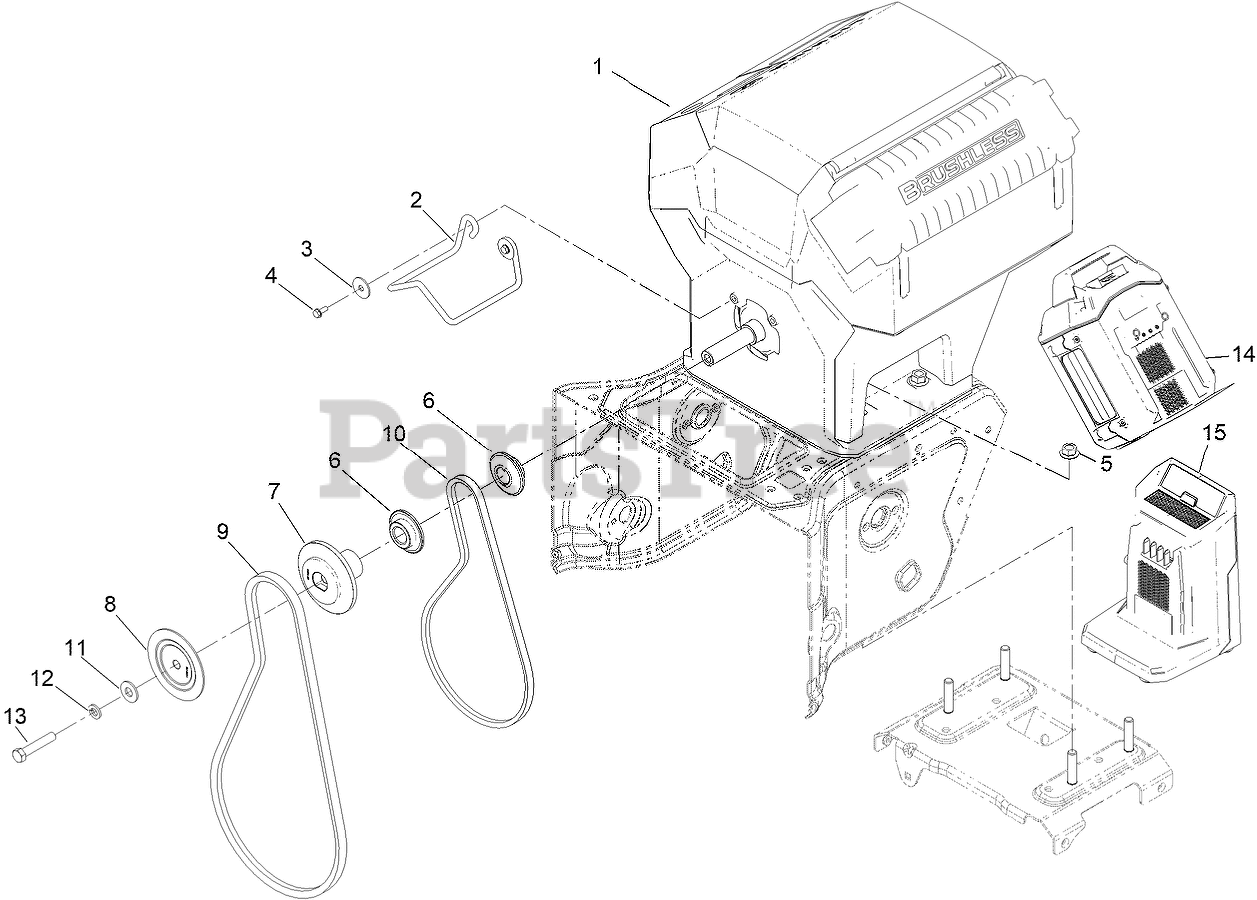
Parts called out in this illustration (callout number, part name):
1	POWERHEAD-60V
2	GUIDE-BELT
3	WASHER-FLAT
4	SCREW-HWH, THD ROLL
5	NUT-LOCK
6	PULLEY-ENGINE, TRACTION
7	PULLEY-AUGER, REAR
8	PULLEY-AUGER, FRONT
9	BELT-V
10	BELT-V
11	WASHER-FLAT
12	WASHER-LOCK
13	SCREW-HH
14	60V BATTERY, 3P 7.5AH
15	CHARGER-60V
